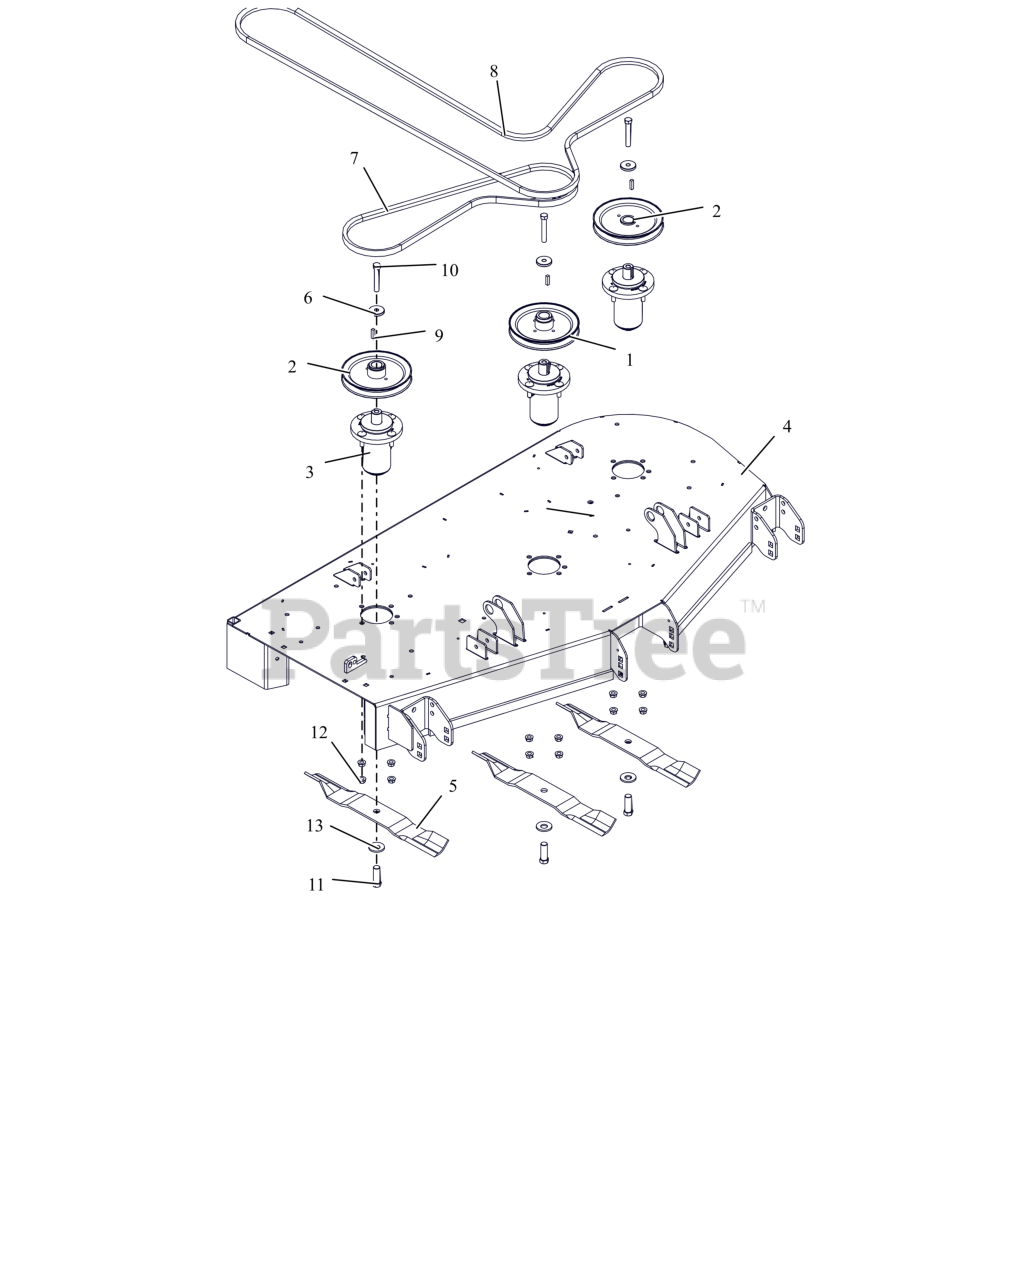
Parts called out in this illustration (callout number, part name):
1	PULLEY, DOUBLE-1"ID X 6.75"OD
2	PULLEY, V-1" ID X 6.75" OD
3	ASM, MAINT FREE ALUM SPINDLE
4	KIT,DECK-52" W/DECALS-ARIENSCE
5	BLADE, 18"
6	RETAINER, SHEAVE
7	V-BELT, B-COGGED
8	V-BELT, HB SECTION
9	KEY, SQ .25X.25X1.00 RC 40-50
10	BLT, HEX .38-16X2.75 G8 ZCC
11	BLT, HEX .62-18X1.75 G8 ZCC
12	NUT-LK-CTR-FLG .375-16 GF ZCC
13	WSHR-BLVL .669X1.535X.138
